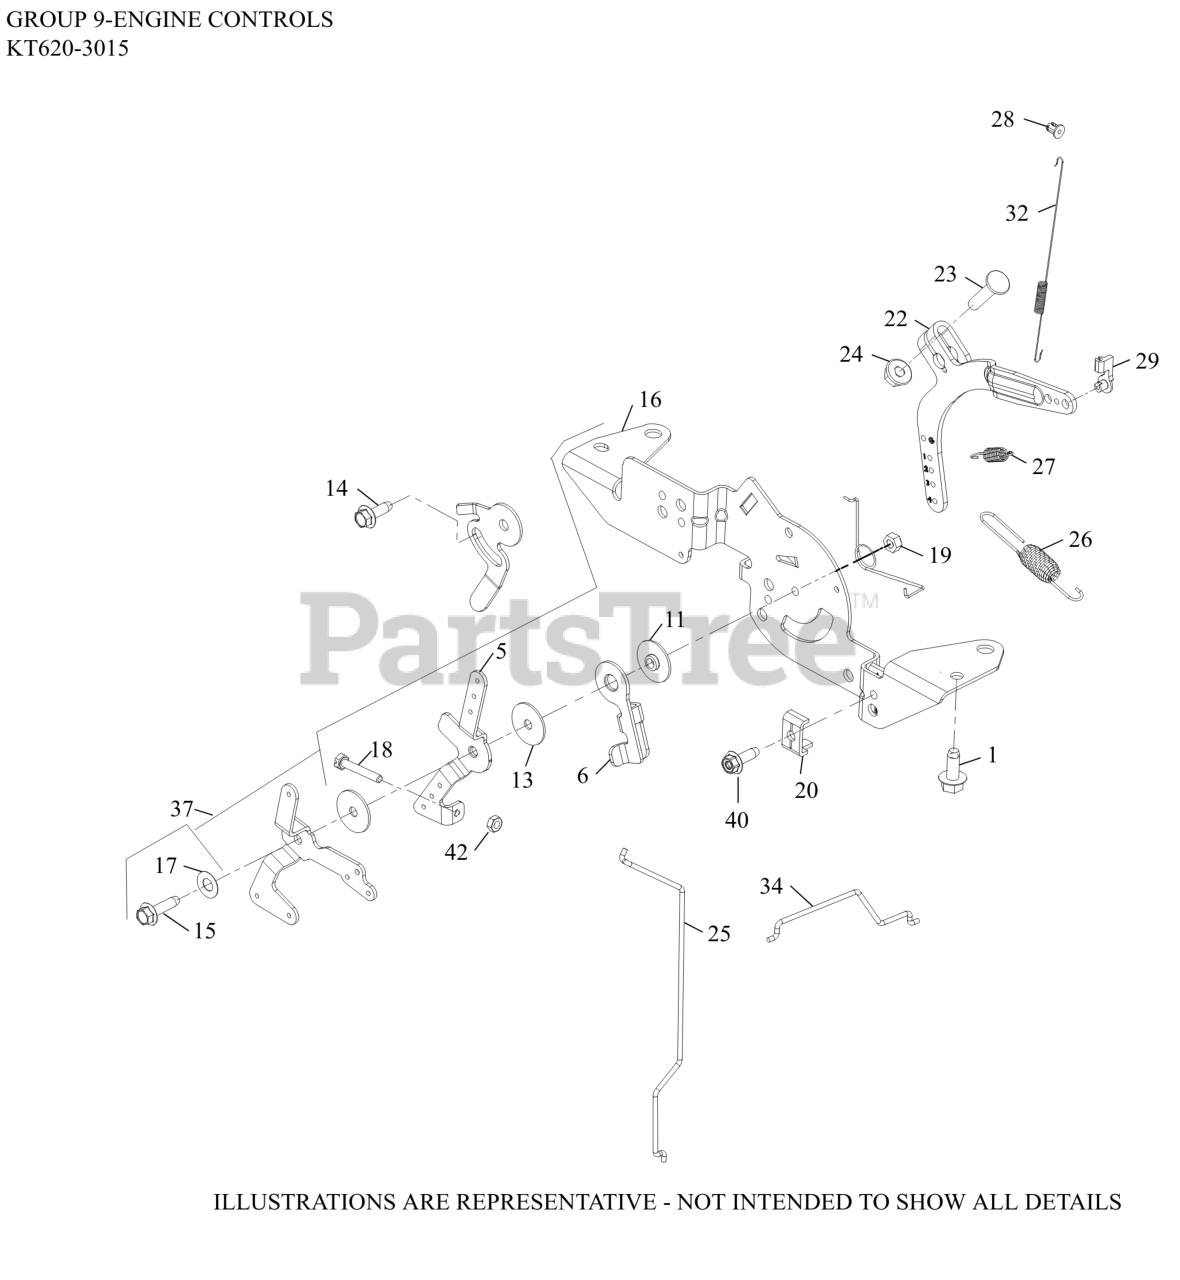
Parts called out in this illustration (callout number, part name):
1	SCREW, THREAD FORMING
5	LEVER, THROTTLE CONTROL
6	LEVER, THROTTLE ACTUATOR
11	SPACER, CONTROL ASSEMBLY
13	WASHER, FLAT 5 MM
14	SCREW, THREAD FORMING
15	SCREW, THD FRM-USE 25 086 473-S
16	BRACKET, SPEED CONTROL
17	WASHER, SPRING 1/4"
18	SCREW, SLT HD CAP M4X0.7X25
19	NUT, LOCK M5X.8
20	CLAMP, CABLE-(#2523753S)
22	LEVER, GOVERNOR - (#2409069S)
23	BOLT, RD HD SQ NECK M6X1.0X25
24	NUT, FLG M6X1.0
26	SPRING, GOVERNOR (ORANGE)
27	SPRING, GOVERNED IDLE
28	BUSHING, LINKAGE RETAINING
29	BUSHING, THROTTLE LINKAGE
32	SPRING, LINKAGE
34	LINKAGE, THROTTLE
37	SPEED CONTROL, ASSEMBLY
40	SCREW, THREAD FORMING
42	NUT, M4X0.7
